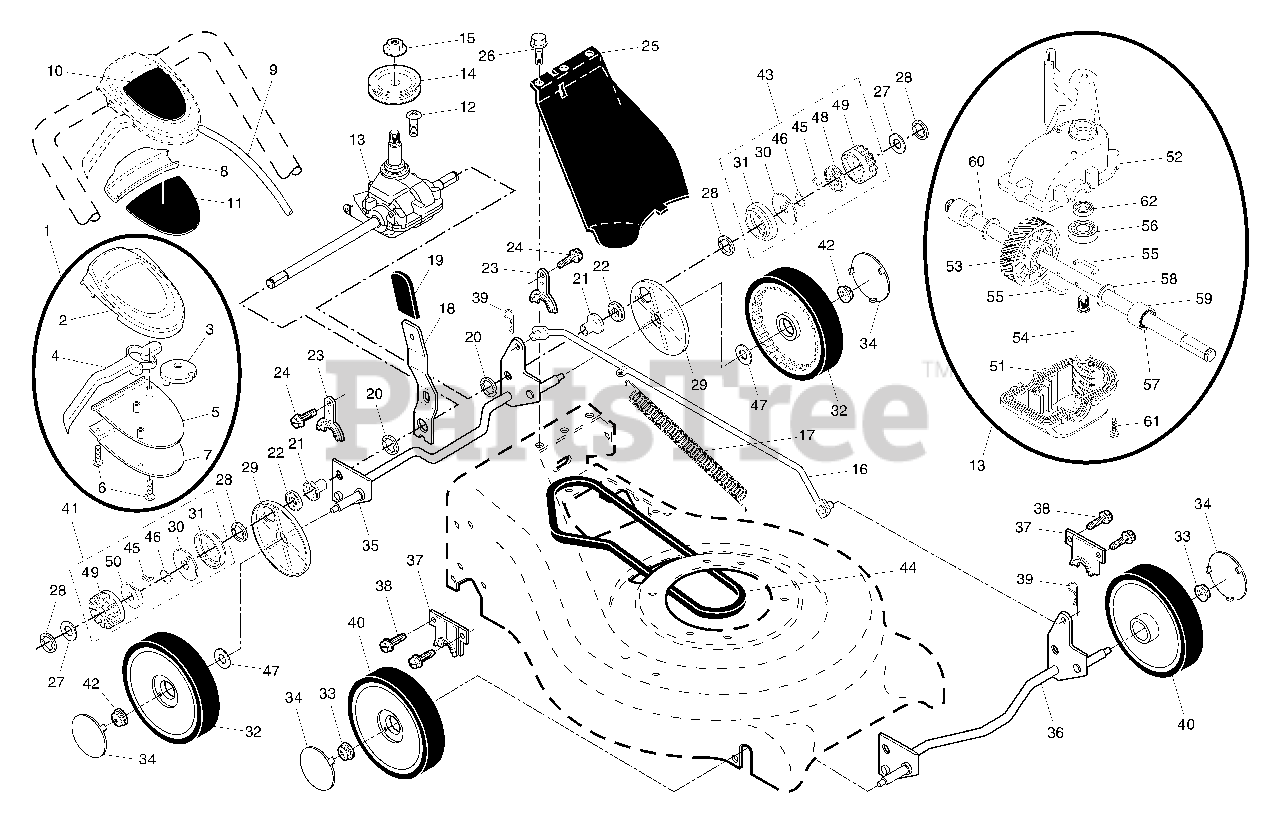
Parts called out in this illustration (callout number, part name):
1	Drive Control Assembly, Auto-Walk
2	Cover, Top, Auto-Walk Drive Control
4	Lever, Auto-Walk Drive Control
5	Cover, Bottom, Auto-Walk Drive Control
6	Screw, Phillips Head #10 x 5/8
7	Plate, Trigger, Auto-Walk Drive Control
8	Cap, Drive Control, Bottom
9	Cable, Drive Control
10	Decal, Drive Control
11	Decal, Drive Control Adjustment (bottom)
13	Gear Case Assembly, Complete
14	Pulley, Drive
15	Nut, Hex, Flanglock, Zinc Plated 3/8-16
16	Rod, Connecting
17	Spring, Extension
18	Spring Selector
19	Knob, Selector Spring
21	Bearing, Support
22	Bearing, Ball
23	Retainer, Drive Assembly, Stamped
24	Screw, Tapping, Hex Head 1/4-20 x .75
25	Cover Drive
26	Screw, Threaded, Rolled #10-25 x .50
28	E-Ring 7/16
29	Cover, Dust, Wheel
30	Disc, Drive
31	Seal, Friction
32	Wheel, Driven, Rear 9 x 2
33	Nut, Hex, Flangelock 3/8-16
34	Hubcap
35	Shaft Assembly, Rear
36	Shaft Assembly, Front
37	Retainer, Front Shaft
38	Screw #12 x 5/8
39	Clip, Retainer
40	Wheel, Front 8 x 2
41	Pinion Assembly, RH
42	Nut, Hex
43	Pinion Assembly, LH
44	V-Belt
46	Spring, Torsion
47	Washer 1/2 x 1-1/2 x .134
48	Retainer, Drive, LH
49	Gear, Pinion
50	Retainer, Drive, RH
51	Case, Lower
52	Case, Upper
53	Gear, 24 Teeth
54	Shaft, Input
55	Wire, Formed
56	Bearing, Ball
57	Seal, Output Shaft
60	Shaft, Output
62	Seal, Input Shaft
